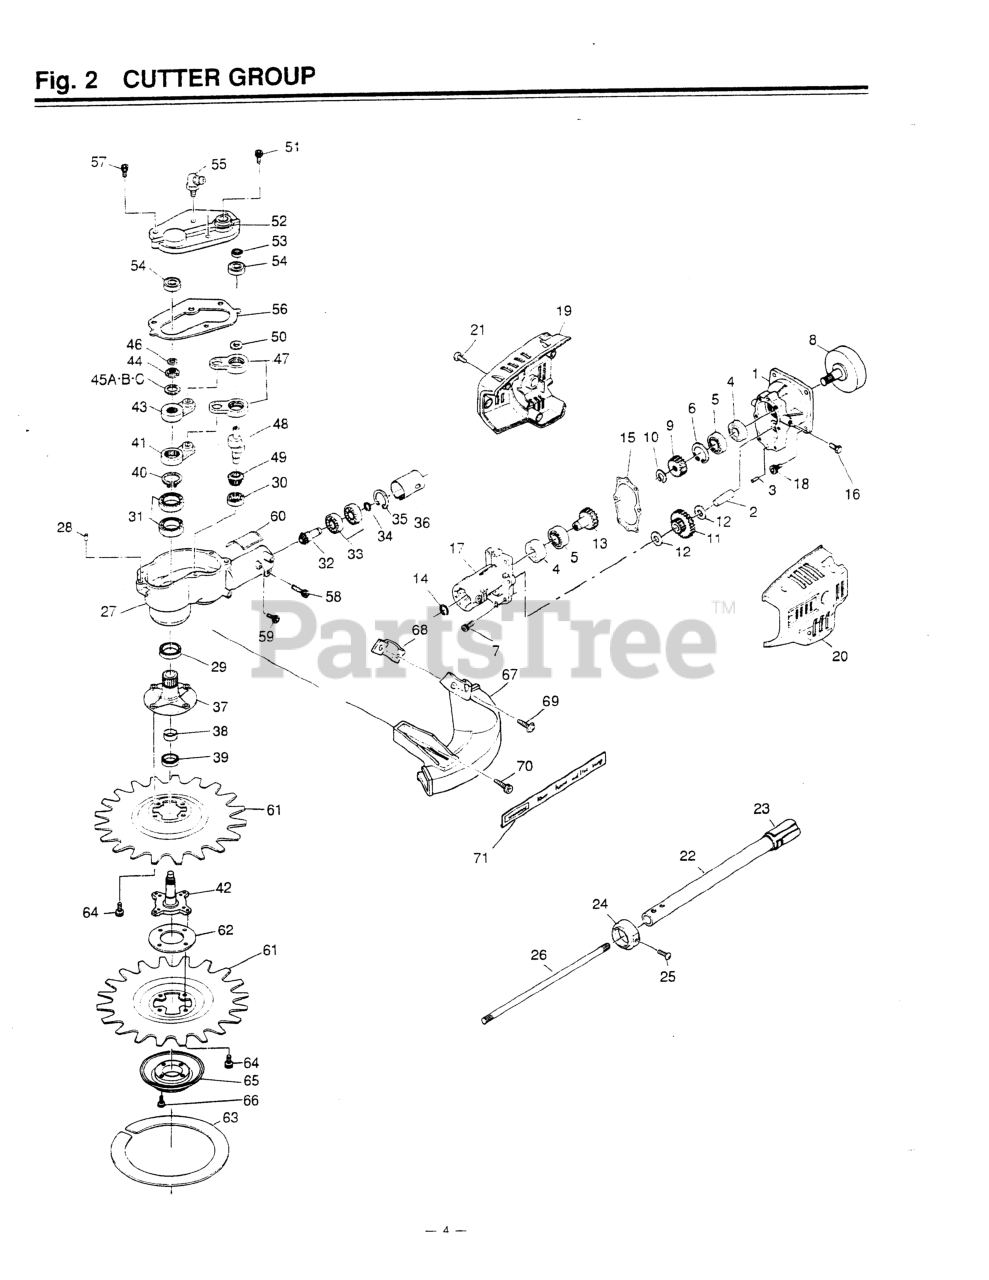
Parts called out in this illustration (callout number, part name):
3	PIN, DOWELL
4	BEARING
5	BEARING
6	RING, SNAP, M28 x 1.2
7	BOLT, M5 X 20
8	DRUM
9	GEAR, PINION
10	RING, SNAP
11	GEAR (RPLS 3805-11330)
12	WASHER
13	GEAR, WHEEL
16	BOLT, M6 x 8
17	CASE, FRONT
19	COVER, RIGHT (RPLS. -11510)
20	COVER, LEFT (RPLS -11520)
22	PIPE COMP (NO LONGER AVAILABLE
24	CAP
25	SCREW, M5 X 10
26	SHAFT (NLA)
27	CASE, CUTTER (USE -98103)
28	PIN, DOWELL
29	SEAL, OIL
31	BEARING
32	PINION
33	BEARING (RPLS T3403-13510)
34	RING, SNAP
35	RING, SNAP, M26 X 1.2
37	SHAFT, OUTER-C
38	BUSHING
39	SEAL, OIL
40	RING, SNAP, M20 x 1.2
41	ARM, LOWER (RPLS -13411)
42	SHAFT, INNER
43	ARM, UPPER (RPLS -13611)
45A	SHIM, 0.3t
45B	SHIM, 0.2T
45C	SHIM, 0.1t
48	CRANKSHAFT
49	GEAR
50	WASHER, M8 x 1.2
51	BOLT
53	SEAL, OIL
54	BEARING (RPLS. T4001-31340)
56	GASKET
57	BOLT, M5 x 20
58	BOLT, M5 X 25
59	SCREW, M5 x 14
60	LABEL, CAUTION
63	PLATE, NAME
64	BOLT, M6 x 8
65	STABILIZER
66	SCREW, M5 X 8
69	SCREW, M6 x 30
70	BOLT
